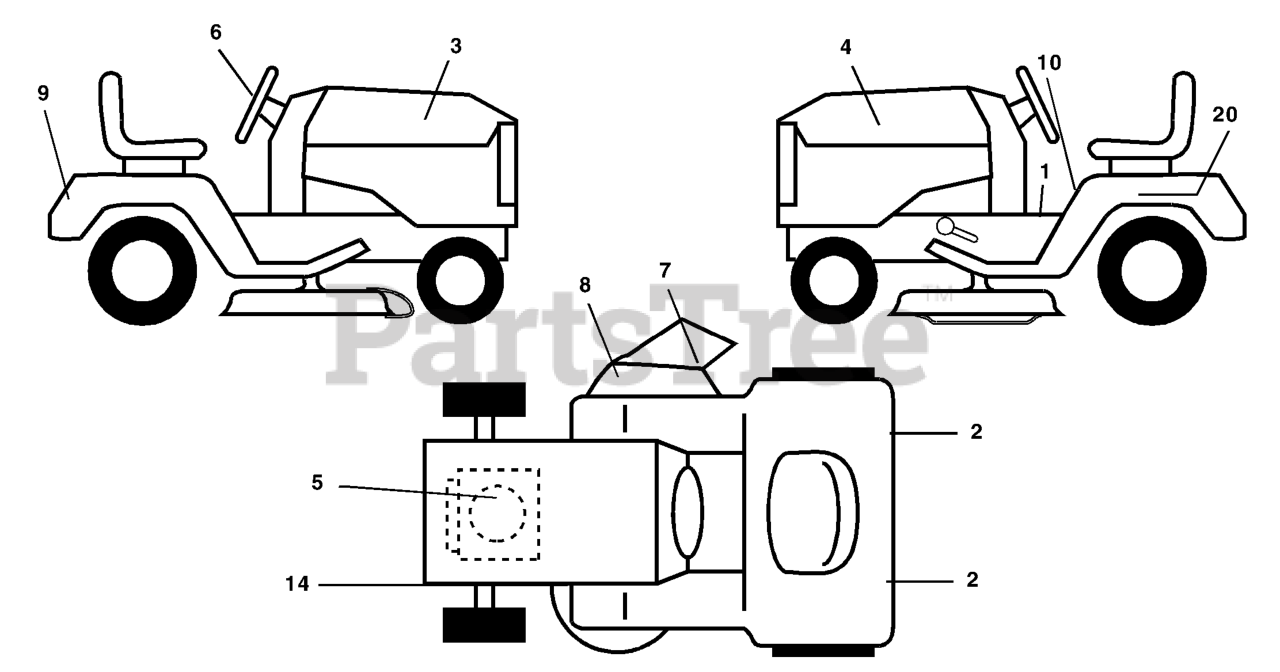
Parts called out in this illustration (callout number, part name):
2	REFLECTOR-TAIL YT
3	DECAL, HOOD RH
4	DECAL, HOOD LH
5	DECAL HOOD CUST. RESP.
6	DECAL.WHEEL.STEERING.HUSQ.PERM
7	DECAL DECK "B" 42"
8	DECAL.WARN.KEEP.HAND.AWAY
9	DECAL, FENDER
10	DECAL FENDER DANGER
14	DECAL V BELT SCHEMATIC
20	DECAL BTRY SYMBOLS
